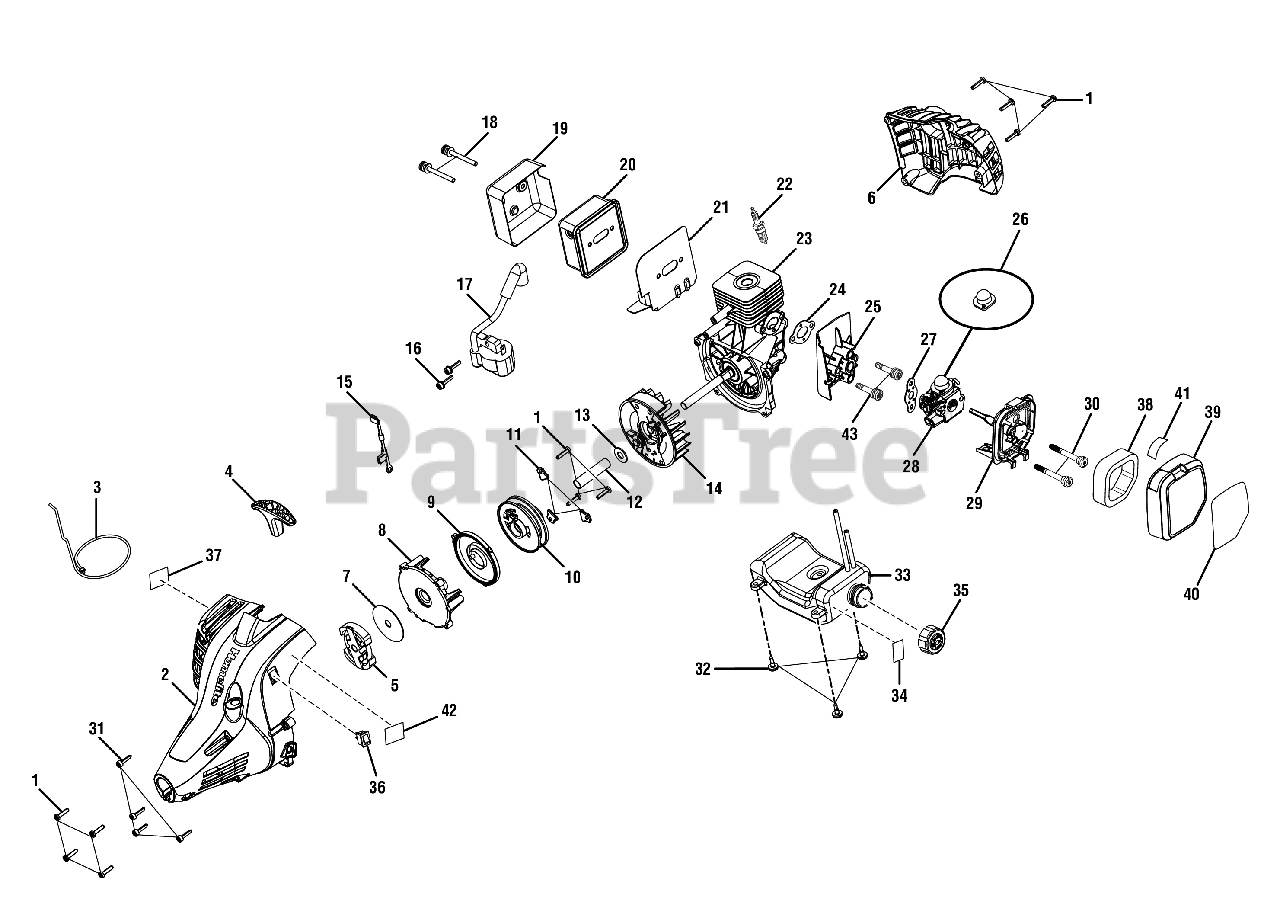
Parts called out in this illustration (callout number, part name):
1	Screw (M4 x 20 mm, T20 Torx Pan Hd. S.T.)
2	Starter Housing Assembly
3	Starter Rope (42 in.)
4	Pulley Handle
5	CLUTCH ASSEMBLY
6	Rear Housing
7	Washer (ID9.63 x OD50.75 x 1.10t)
8	Starter Housing
9	Spring & Container Assembly
10	Starter Pulley Assembly
11	Pulley Retainer
12	Spacer Tube
13	Washer (ID9.75 x OD20 x 1.6t)
14	Flywheel Assembly
15	Lead Assembly
16	Screw w/Washer (M4 x 19 mm, T20 Torx Pan Hd. S.T.)
17	Ignition Module
18	Screw w/Washers (10-24 x 2-1/8 in., T25 Torx Truss Hd.)
19	Muffler Housing
20	Muffler Assembly (Non "A" versions)
21	Muffler Gasket
22	SPARK PLUG CHAMPION - RCJ-6Y
23	Short Block Assembly
24	Inner Heat Dam Gasket
25	Heat Dam Deflector
28	Carburetor Assembly
29	Airbox Base Assembly
30	Screw (M5 x 45 mm, T20 Torx Truss Hd.)
31	Screw w/Washer (M4 x 16 mm, T25 Torx Truss Hd.)
32	Shoulder Screw w/Washer (M4 x 14 mm, T25 Torx Truss Hd.)
33	Fuel Tank w/Label & Cap Assembly
34	Fuel Tank Warning Label
35	Fuel Cap Assembly
36	Stop Switch (Momentary Contact)
37	Warning Label (Combustion)
38	Air Filter (Element)
39	Air Box Cover
40	Starting Label
41	Choke Label
42	Primer Bulb Location Label
43	Screw w/Washers (M5 x 30 mm, T25 Torx Pan Hd.)
